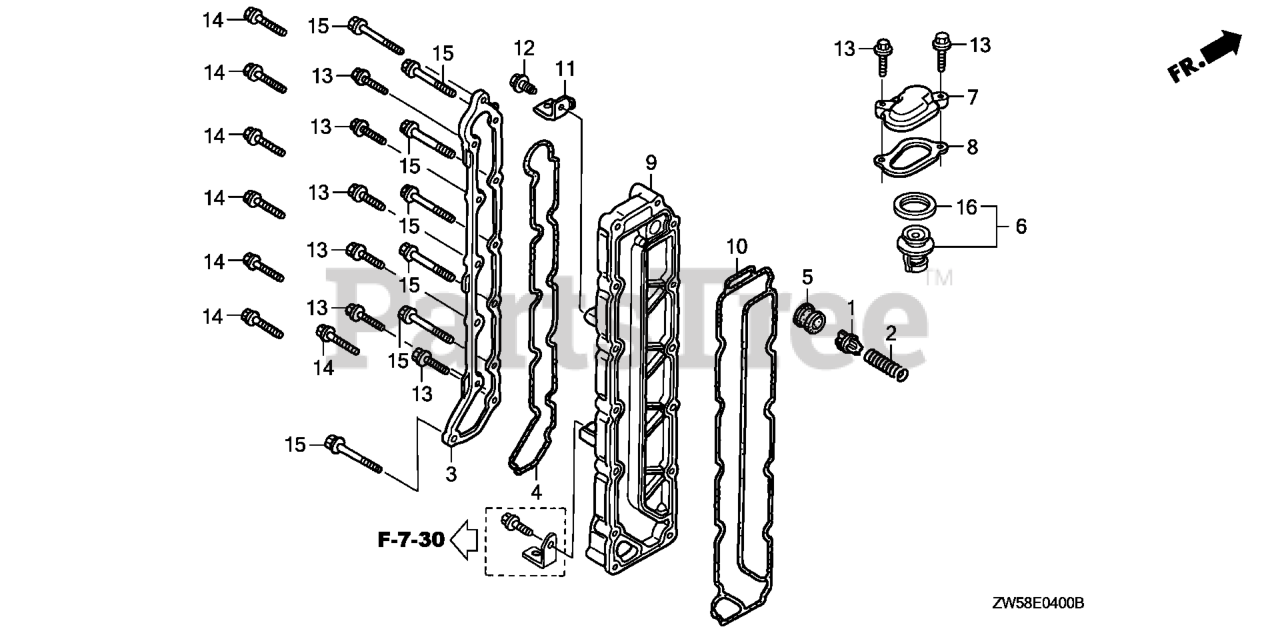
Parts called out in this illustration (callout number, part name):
1	VALVE, RELIEF
2	SPRING, RELIEF VALVE
3	COVER, RELIEF VALVE
3	COVER, RELIEF VALVE *NH8* (DARK GRAY)
4	GASKET, RELIEF VALVE COVER
5	GASKET, RELIEF VALVE
6	THERMOSTAT ASSY.
7	COVER, THERMOSTAT
8	GASKET, THERMOSTAT COVER
9	COVER, WATER JACKET *NH8* (DARK GRAY)
10	GASKET, WATER JACKET COVER
11	STAY A, IGNITION WIRE CLAMP
12	BOLT, FLANGE (6X12) (CT200)
13	BOLT, FLANGE (6X20)
14	BOLT, FLANGE (6X25)
15	BOLT, FLANGE (6X45)
16	RUBBER, RING
